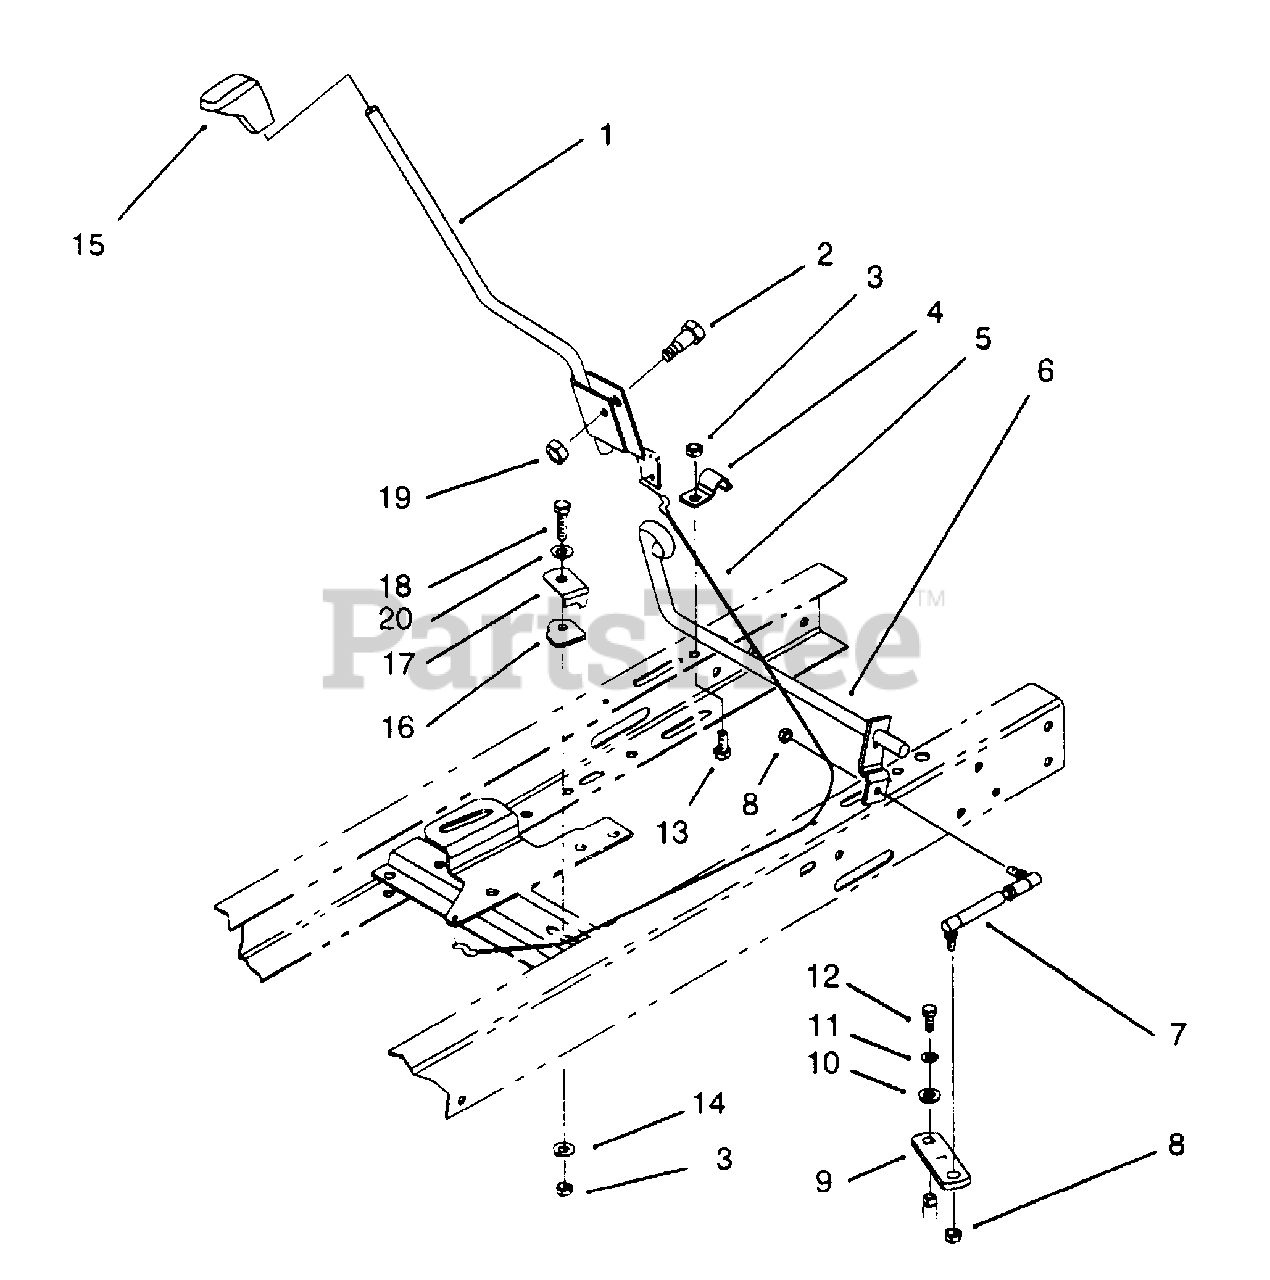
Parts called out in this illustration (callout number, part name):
1	Lever-Shift
2	Bolt-Shoulder
3	Nut-Lock
4	Clamp-Shift Pivot
5	Cable-Shotgo
6	Pivot-Shift
7	Rod-Shift Tie
8	Nut-Lock
9	Lever-Trans. Shift
10	Washer-Hardened
11	Washer-Lock
12	Screw-Hex Hd. Cap
13	Screw-Hex Hd. Cap
14	Washer-Flat
15	Knob-Shift
16	Guide-Cable
17	Keeper-Cable
18	Bolt-Carriage
19	Nut-Lock
20	Washer-Flat
